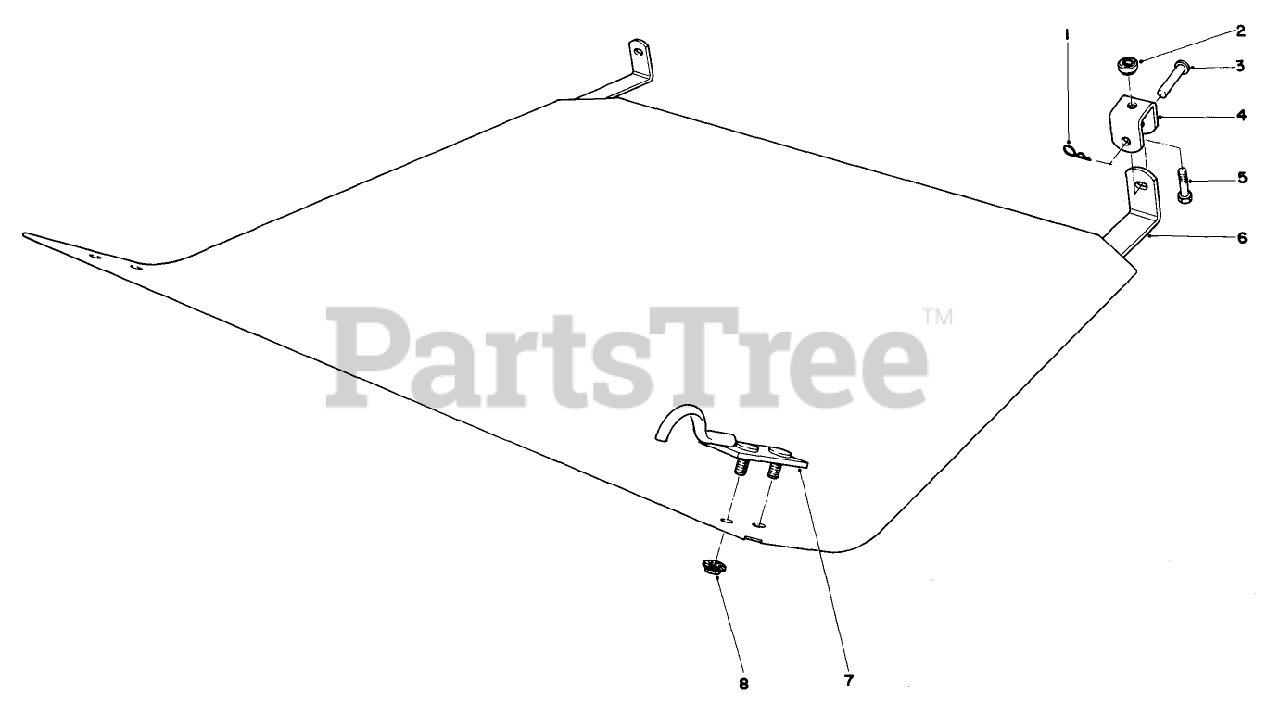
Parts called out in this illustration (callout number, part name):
1	PIN-HAIR
2	SPACER
3	CLEVIS
4	Hanger-Belly Shield
5	SCREW-HH
6	Belly Shield
7	Belly Shield Hook
8	NUT-HF
